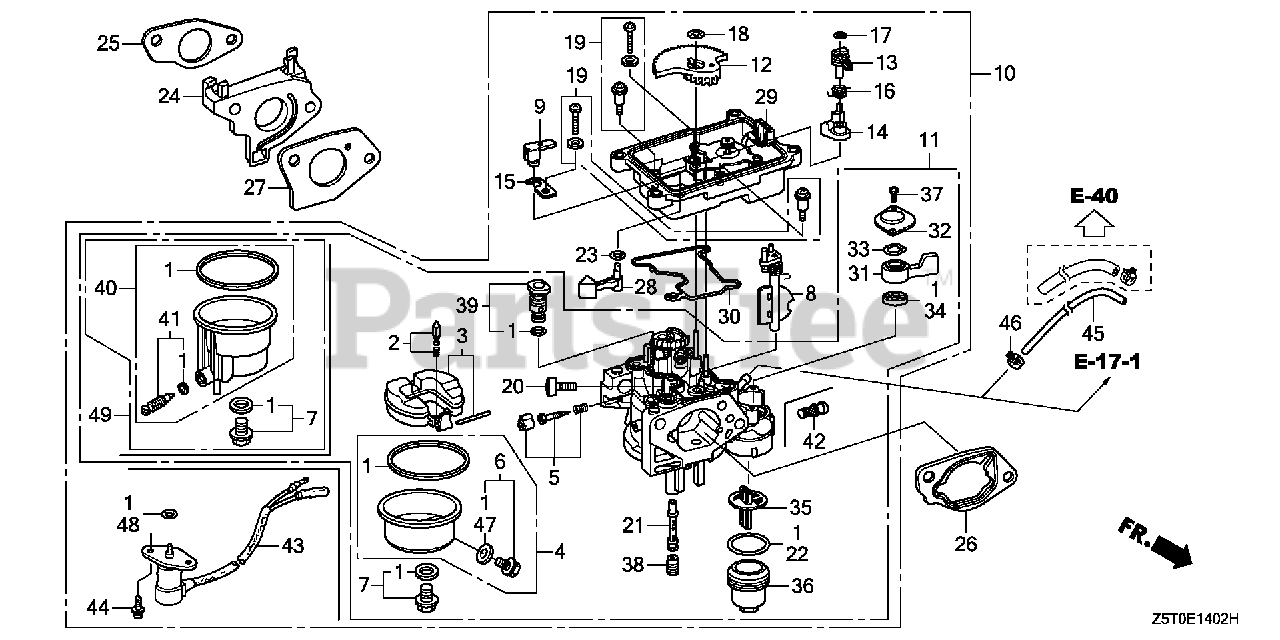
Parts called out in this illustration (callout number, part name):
1	GASKET SET
2	VALVE SET, FLOAT
3	FLOAT SET (CARBURETOR NO.)
5	SCREW SET
9	ARM, MANUAL START
10	CARBURETOR ASSY. (BEC5A A)
11	CARBURETOR SET
12	GEAR, MIDDLE
13	ARM, CHOKE
14	LEVER, CHOKE CONTROL
16	SPRING, TORSION COIL
17	CLIP, SPECIAL
18	CLIP, SPECIAL
20	SCREW, STOP
21	NOZZLE, MAIN
23	O-RING (CARBURETOR NO.)
24	INSULATOR, CARBURETOR
25	GASKET, CARBURETOR INSULATOR
27	GASKET, CARBURETOR
28	LEVER, MANUAL START
29	CASE, MOTOR
38	JET, MAIN (#95)
38	JET, MAIN (#98) Use from Engine SN BE87A A to BE87A A.
38	JET, MAIN (#100) Use from Engine SN BE87A A to BE87A A.
39	JET SET, PILOT (#45) (CARBURETOR NO.)
40	CHAMBER SET, FLOAT
41	SCREW SET, DRAIN (ADVENTURE GREEN) (CARBURETOR NO.)
43	VALVE ASSY., SOLENOID
44	SCREW-WASHER (5X12)
48	O-RING (CARBURETOR NO.)
